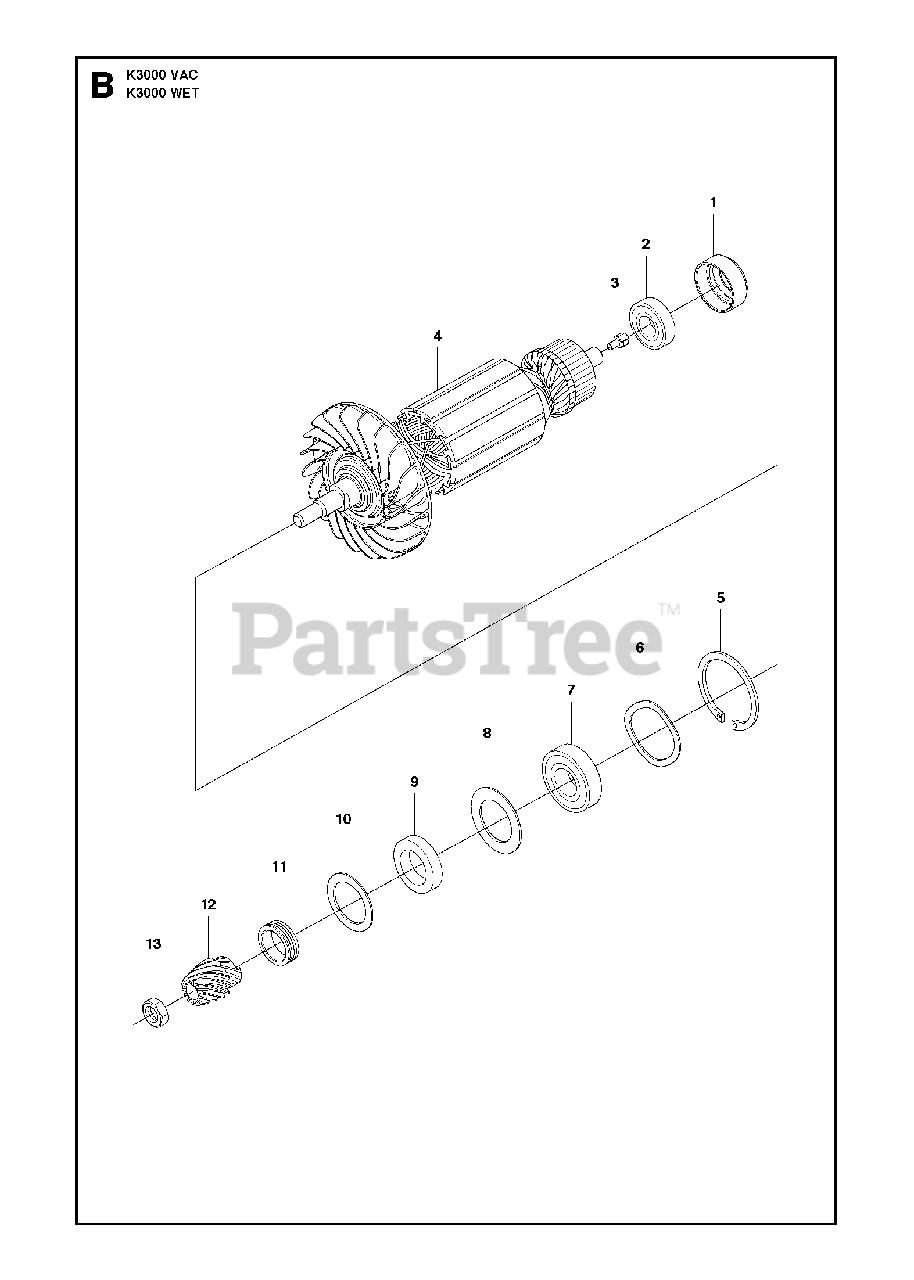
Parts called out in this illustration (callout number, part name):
4	ROTOR100 - 120V
6	SPRING WASHER
7	BALL BEARING
